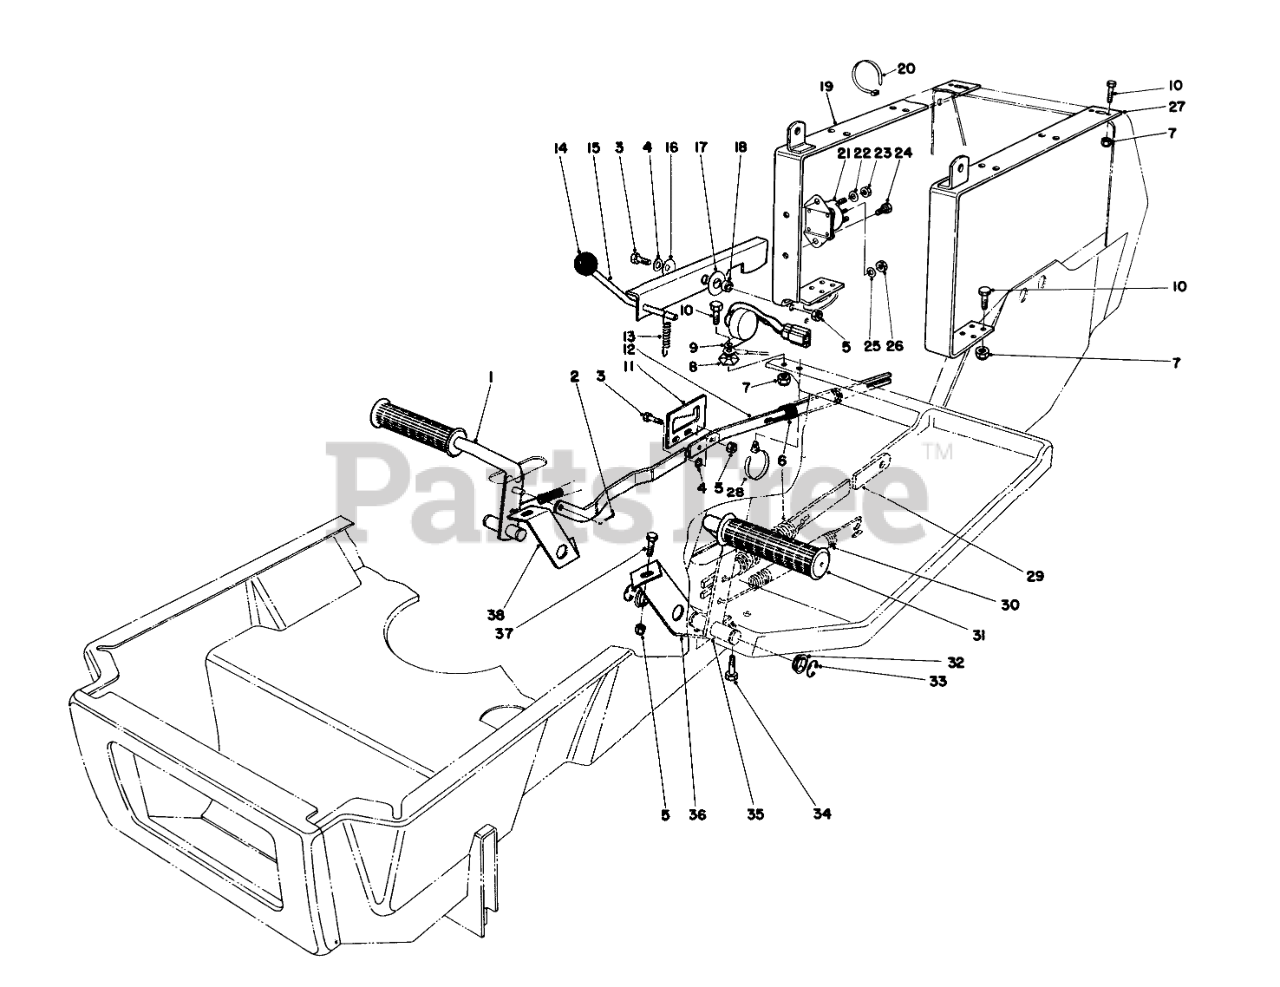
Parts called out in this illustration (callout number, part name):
1	BRAKE PEDAL WA BO
2	PIN-COTTER
3	SCREW-HH
4	WASHER-PLAIN
5	NUT-LOCK, NI
6	EXT SPRING O
7	NUT-LOCK, NI
8	Washer
9	Module Interlock
10	SCREW-HH
11	LATCH PLT-BRAKE ROD
12	LINK BRAKE ROD WAB
13	CONT ROD SPRING 0
15	PARKING BRAKE WA B
16	WASHER-BELLEVILLE
17	WASHER-PLASTIC
18	SPACER
19	RR BODY STRAP WA B
20	TIE-CABLE
21	SOLENOID
22	WASHER-LOCK
23	NUT-JAM, BRASS
24	SCREW
25	WASHER-LOCK
26	NUT-HEX
27	LH RR BODY STRAP WA B
28	TIE-MOUNT, PUSH
29	CLUTCH ROD LINK B
30	SPRING-EXTENSION
31	FOOT PAD
32	Nyliner
33	E-RING
34	SCREW-HWHTF
35	CLUTCH PEDAL WA BO
36	LH PEDAL SUPT B
37	SCREW-HH
38	RH PEDAL SUPT B
